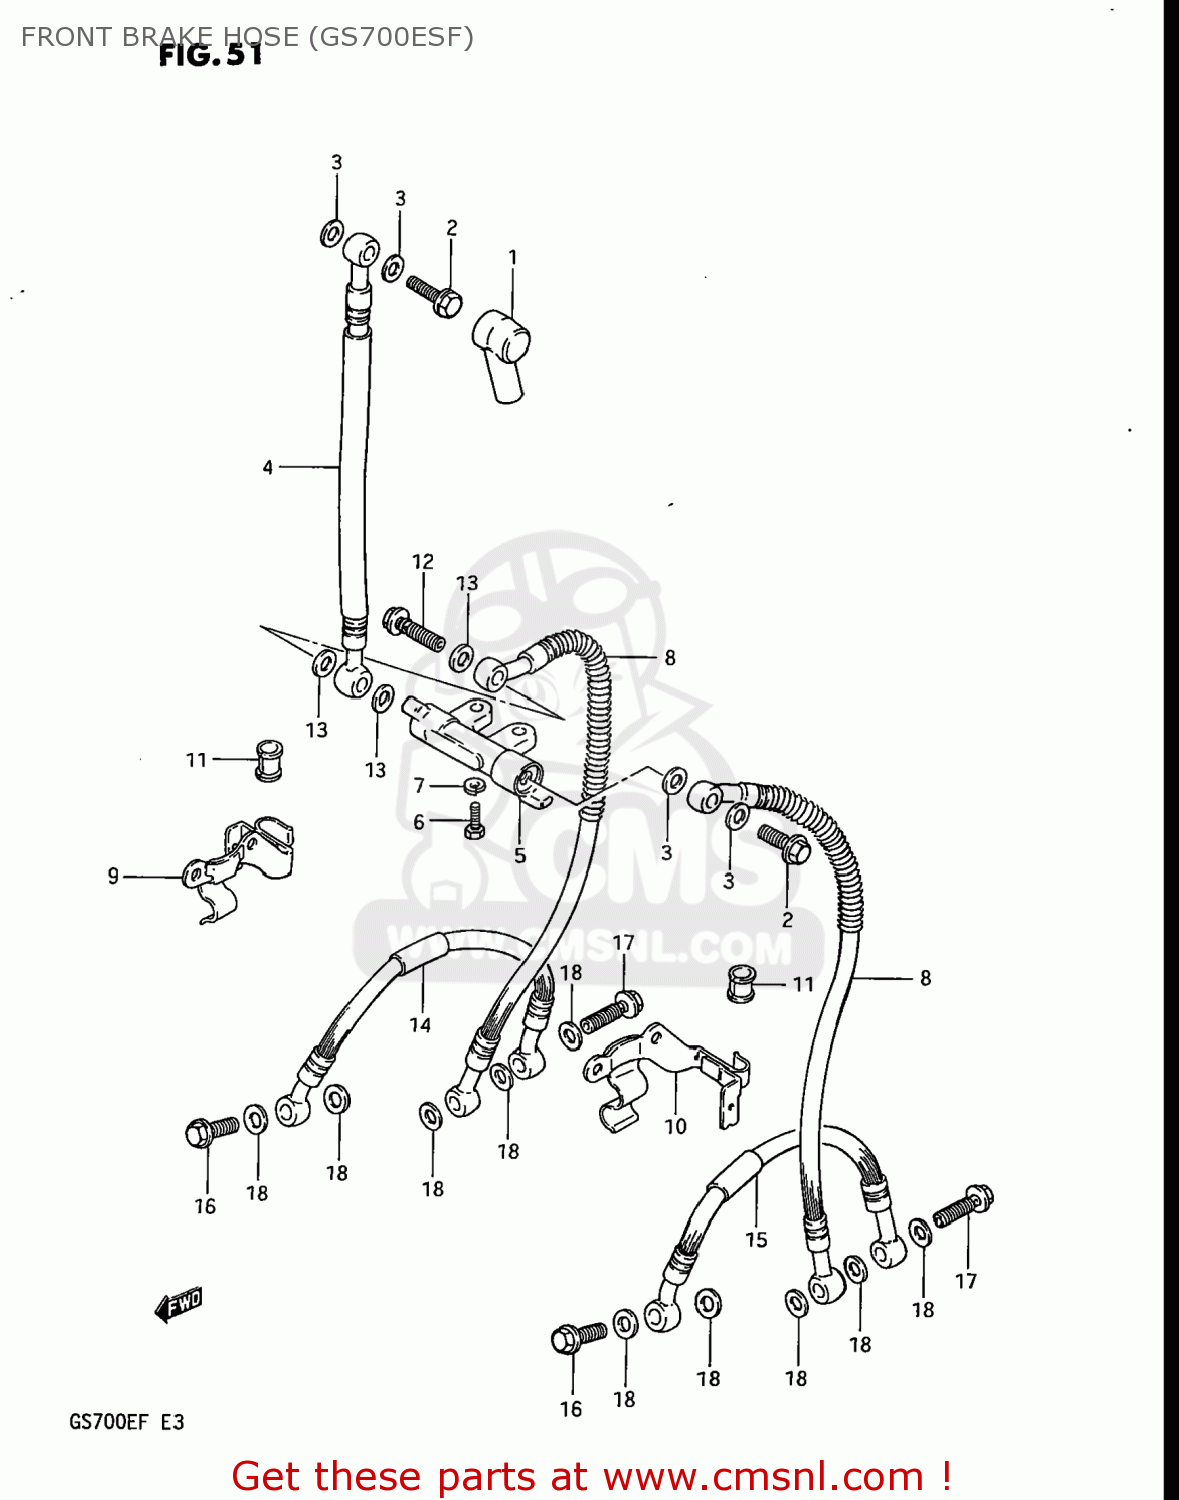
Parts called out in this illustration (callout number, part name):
1	BOOT,MASTER CYLINDER
2	BOLT UNION
3	WASHER(10X15X1.5)
4	HOSE,FR BRAKE NO.1
5	JOINT,BRAKE HOSE
6	BOLT
7	LOCK WASHER
8	HOSE,FRONT BRAKE NO.2
9	CLAMP,FRONT BRAKE HOSE
10	CLAMP,BRAKE HOSE,LEFT
11	BUSH,BRAKE HOSE GUIDE,NO.2
12	BOLT UNION
13	WASHER(10X15X1.5)
14	HOSE,ANTI-NOSE DIVE
15	HOSE,ANTI-NOSE DIVE
16	BOLT UNION
17	BOLT UNION
18	WASHER(10X15X1.5)
